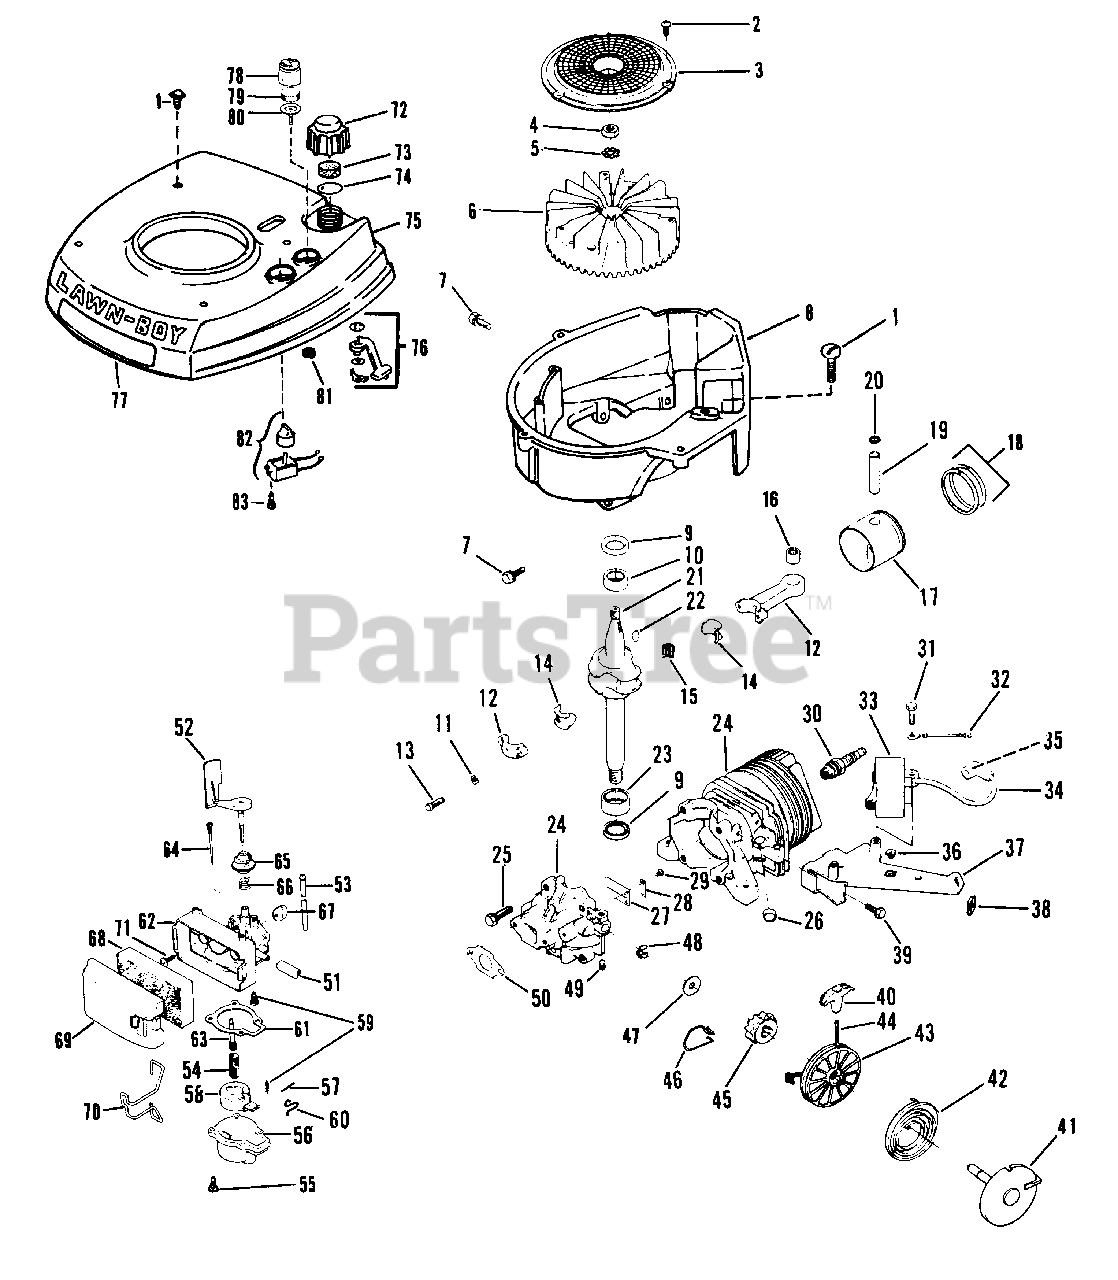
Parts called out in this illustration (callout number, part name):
1	Screw
2	Screw-Flywheel Screen
3	Screen-Flywheel
4	Nut-Acorn
5	Lockwasher
6	Flywheel Assembly
7	Screw
8	Base-Shroud
9	Oil Seal
10	Bearing-Upper
11	Lockplate
12	Connecting Rod Assembly
13	Screw
14	Liner-Split
15	Needle Bearing Set
16	Bearing Assembly
17	Piston & Ring Set
18	Ring Set
19	Wrist Pin
20	Retaining Ring
21	Crankshaft
22	Key-Flywheel
23	Bearing-Lower
24	Cylinder & Crankcase Cover Assembly
25	Screw-Cover to Crankcase
26	Plug
27	Reed
28	Plate-Reed Hold Down
29	Screw-Reed to Crankcase Cover
30	Spark Plug
31	Screw-C.D. Mounting
32	Lead Assembly-Ignition
33	C.D. Ignition Module & Lead Assembly
34	High Tension Lead
35	Spring Terminal
36	Grommet-C.D. Bracket
37	Bracket-C.D. Mounting
38	Clip-"U"
39	Screw
40	Handle-Starter
41	Cup & Pin Assembly
42	Spring
43	Pulley
44	Rope
45	Pinion
46	Spring-Drag
47	Washer
48	Retainer
49	Set Screw-Starter Assembly
50	Gasket-Carburetor to Crankcase Cover
51	Fuel Line
52	Air Vane & Shaft
53	Tube-Primer
54	Filter-Carburetor
55	Screw-Float Chamber
56	Float Chamber
57	Pin-Float
58	Float
59	Float Valve & Seat Assembly
60	Clip
61	Gasket
62	Carburetor Body
63	Nozzle
64	Needle Adj. Assy.
65	Collar
66	Spring
67	Disk-Throttle
68	Element-Air Filter
69	Cover-Air Filter
70	Retainer-Filter Cover
71	Screw-Carburetor Mounting
72	Fuel Cap
73	Baffle
74	Gasket
75	Shroud-Scamp
75	Shroud-Utility
76	Fuel Shut-Off Assembly
77	Decal-Scamp
77	Decal-Utility
78	Bulb-Primer
79	Filter-Primer Bulb
80	Base-Primer
81	Nut-Primer
82	Switch-On-Off
83	Screw-Switch M Mounting
